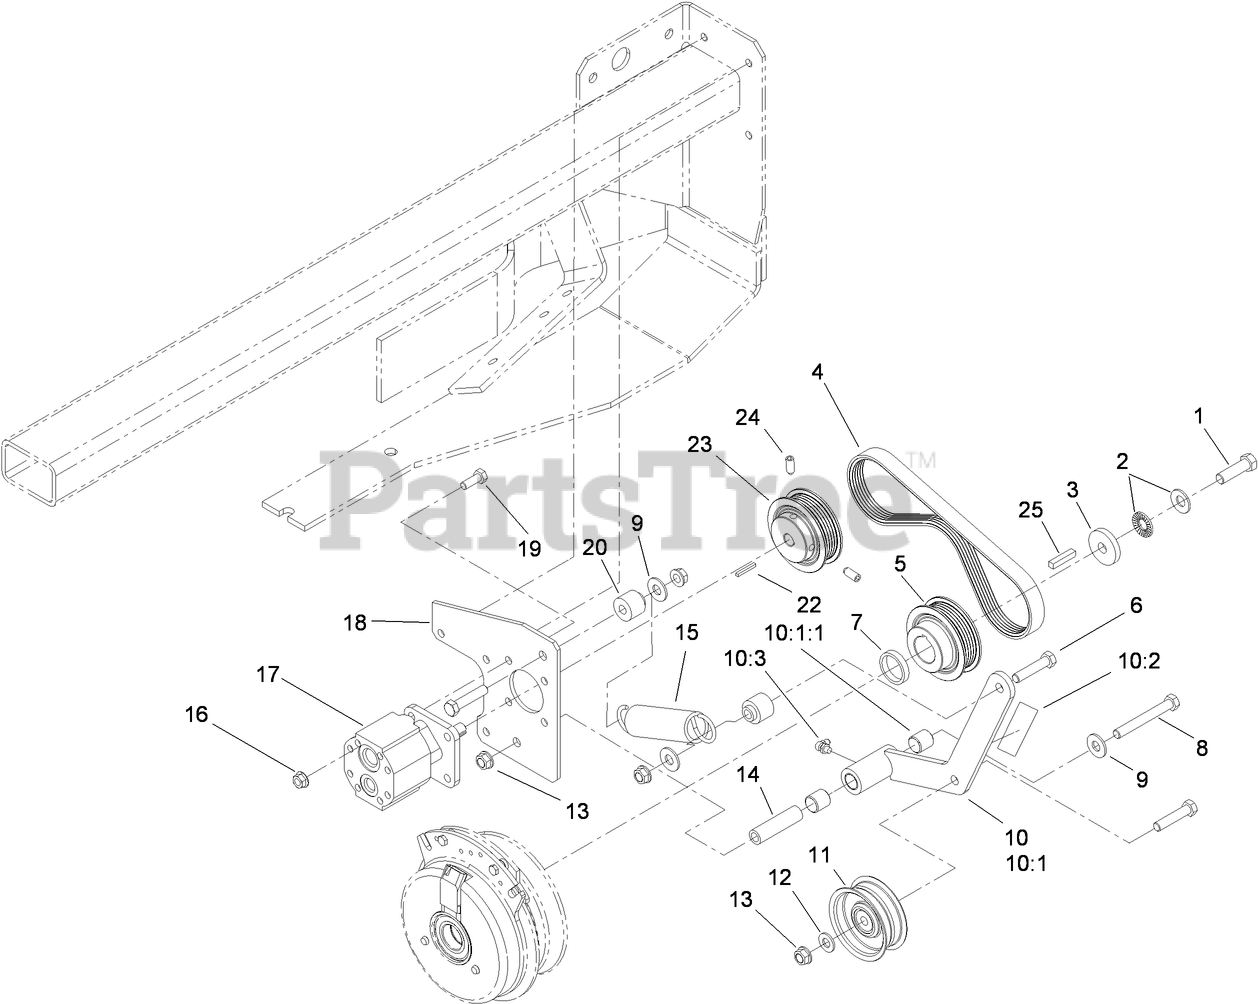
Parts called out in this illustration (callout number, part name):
1	SCREW-HH
2	WASHER-SPRING
3	WASHER-CLUTCH
4	BELT-POLY V
5	SHEAVE-5 RIB
6	SCREW-HH
7	SPACER-PUMP DRIVE, FAN
8	SCREW-HH
9	WASHER-FLAT
10	WHEEL PUMP TENSION ASM
10:1	TENSIONER ASM
10:1:1	SLEEVE-BEARING
10:2	DECAL-COVER, MISSING
10:3	FITTING-GREASE, 90 DEG
11	SHEAVE-IDLER
12	WASHER-FLAT
13	NUT-HHF, WHIZ
14	BUSHING-PIVOT, IDLER
15	SPRING-EXTENSION
16	NUT-LOCK, NI
17	PUMP-FAN, COOLING
18	PLATE-MATING, FAN PUMP
19	SCREW-HH
20	SPACER-SPRING, FAN PUMP
22	KEY-SQUARE
23	SHEAVE-5 RIB
24	SCREW-SET, HSH
25	KEY-SQUARE
